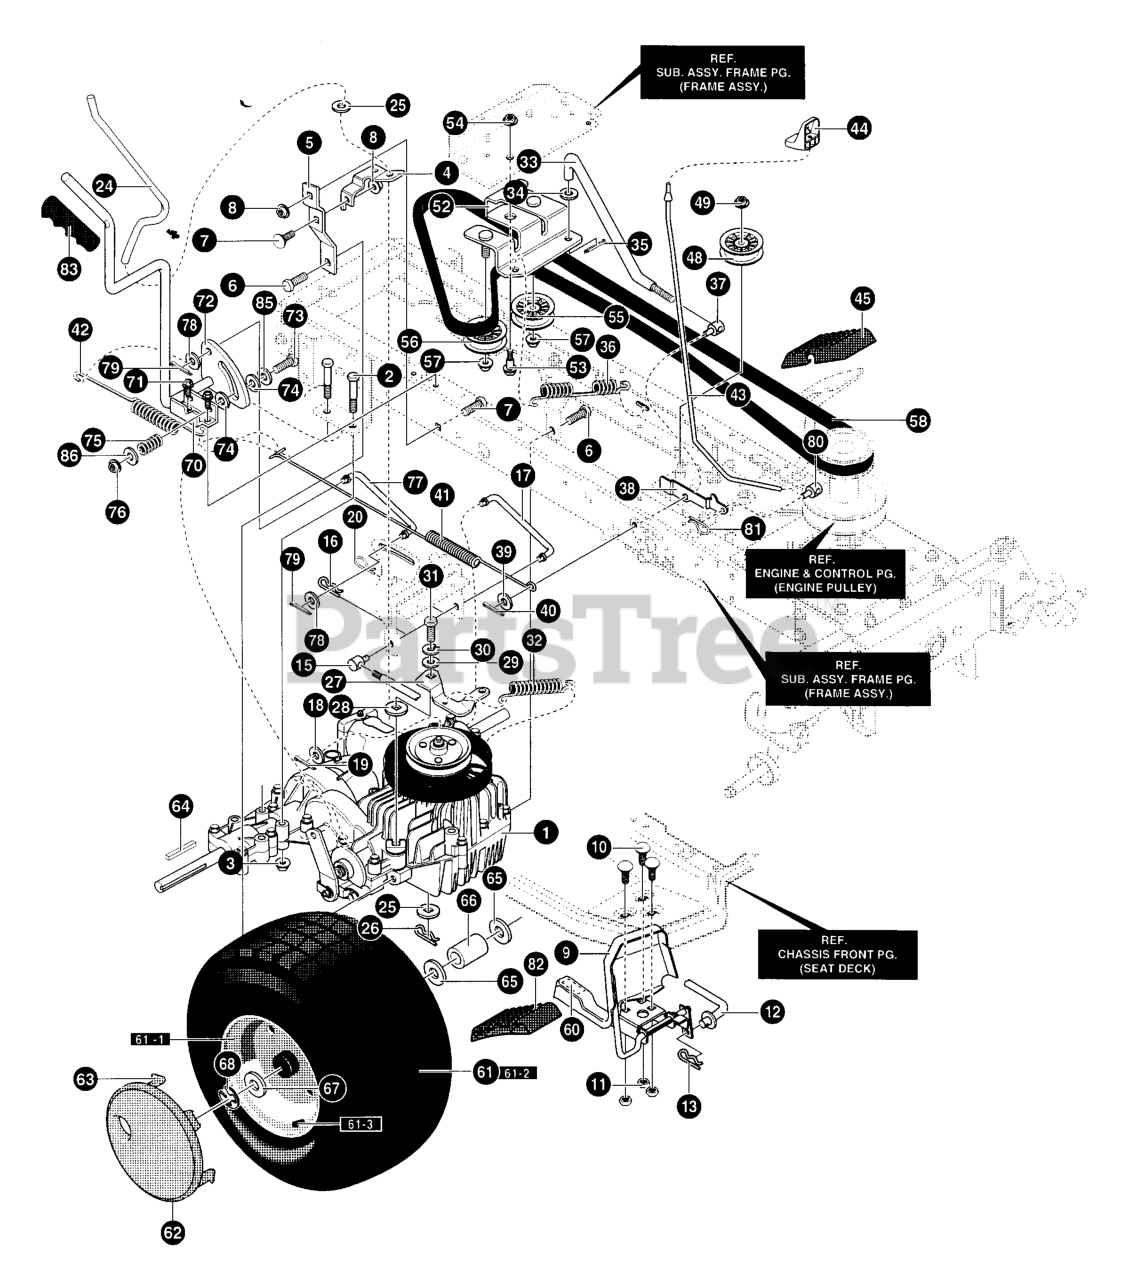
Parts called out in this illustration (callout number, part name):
1	Transaxle, Peerless **
2	SCREW, 5/16-18 x 2.50
3	NUT, 5/16-18
4	BRACKET, DISCONNECT
5	TORQUE STRAP
6	SCREW, 5/16-18 x 0.75
7	BOLT
8	NUT, 5/16-18
9	ASSEMBLY, PEDAL
10	BOLT
11	NUT, 5/16-18
12	ROD, PEDAL LINK
13	PIN, HAIR
15	ADJUSTING NUT 1/2-13
16	PIN, HAIR
17	ROD HYDRO LINK
18	WASHER, FLAT
19	PIN, COTTER
20	PIN, HAIR
24	ROD HYRO LINK
25	Washer
26	PIN, COTTER
27	ARM DISCONNECT
29	WASHER, FLAT
32	SPRING, EXTENSION
33	ROD, CLUTCH
34	Washer
35	PIN, COTTER
36	SPRING, CLUTCH
37	NUT, ADJUSTING
38	LATCH, PARK BRAKE
39	WASHER, FLAT
40	PIN, COTTER
41	SPRING, EXTENSION
42	SPRING, TENSION
43	ROD, PARKING BRAKE
44	KNOB, PARKING BRAKE
45	PAD, CLUTCH/BRAKE
48	PULLEY, IDLER
49	NUT, 3/8-16
52	BRACKET IDLER
54	NUT, 3/8-16
55	PULLEY, IDLER
56	PULLEY, V- IDLER 3"
57	NUT, 3/8-16
58	BELT, MOTION DRIVE
60	PAD, TOE
61	TIRE & RIM 20X10-8
61-1	VALVE STEM
61-2	RIM, CARL
61-3	TIRE 20X10-8
62	HUB CAP 8"
63	CLIP, HUBCAP
64	KEY, SQUARE
65	WASHER, FLAT
67	WASHER, FLAT
68	RING, RETEX
70	BRACKET, HAND CONTROL
71	SCREW 5/16-18X.75
72	LEVER HAND CRUISE
73	BOLT 5/16-18X.5
74	WASHER, FRICTION
75	SPRING - COMP
76	NUT, 5/16-18
77	LINK, CRUISE CONTROL
78	Washer
79	PIN, COTTER
80	CLEVIS, PARKING BRAKE
81	PIN, COTTER
82	PAD, SPEED CONTROL PEDAL
83	GRIP, 7/16" I D
85	WASHER, FLAT
86	WASHER, FLAT
